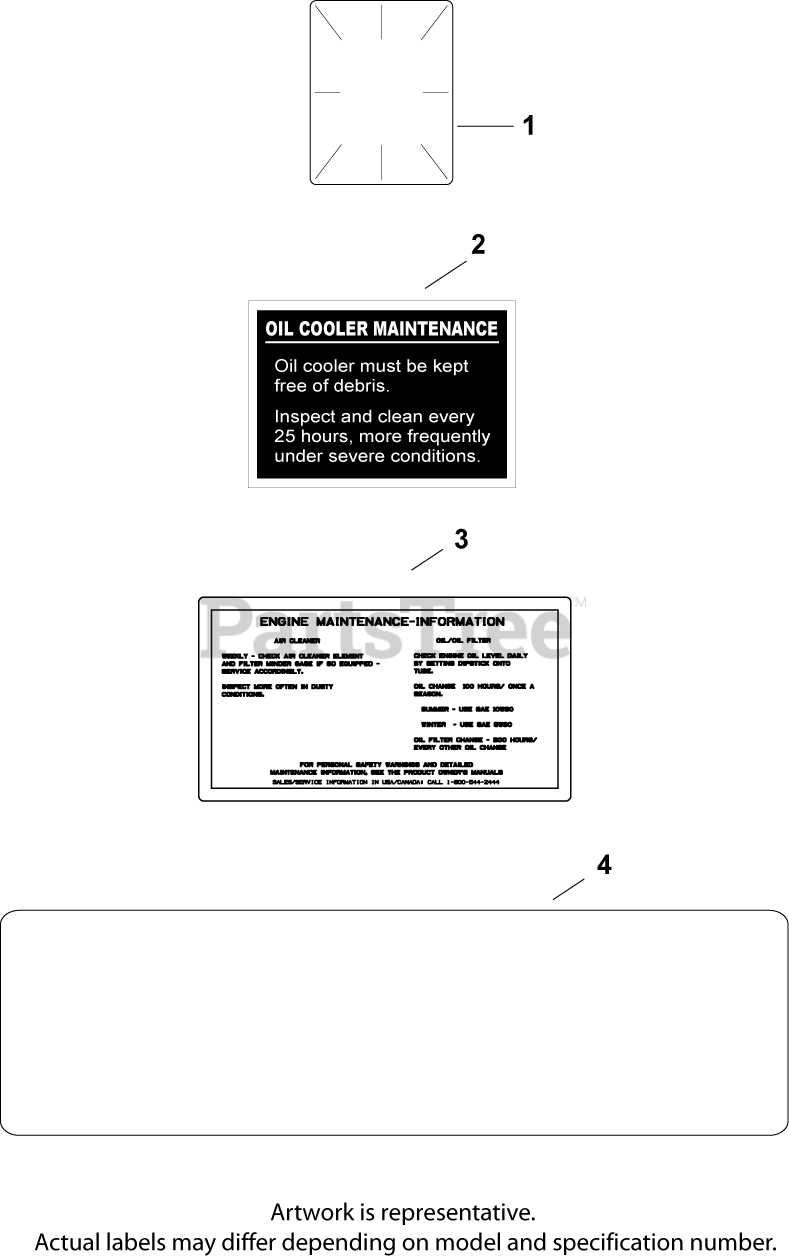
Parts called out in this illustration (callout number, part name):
1	DECAL, CLEAR LAMINATE USE 25 113 70-S
2	DECAL, OIL COOLER - (#DSC)
3	DECAL, AIR CLEANER - (#DSC)
4	DECAL, 25 HP
